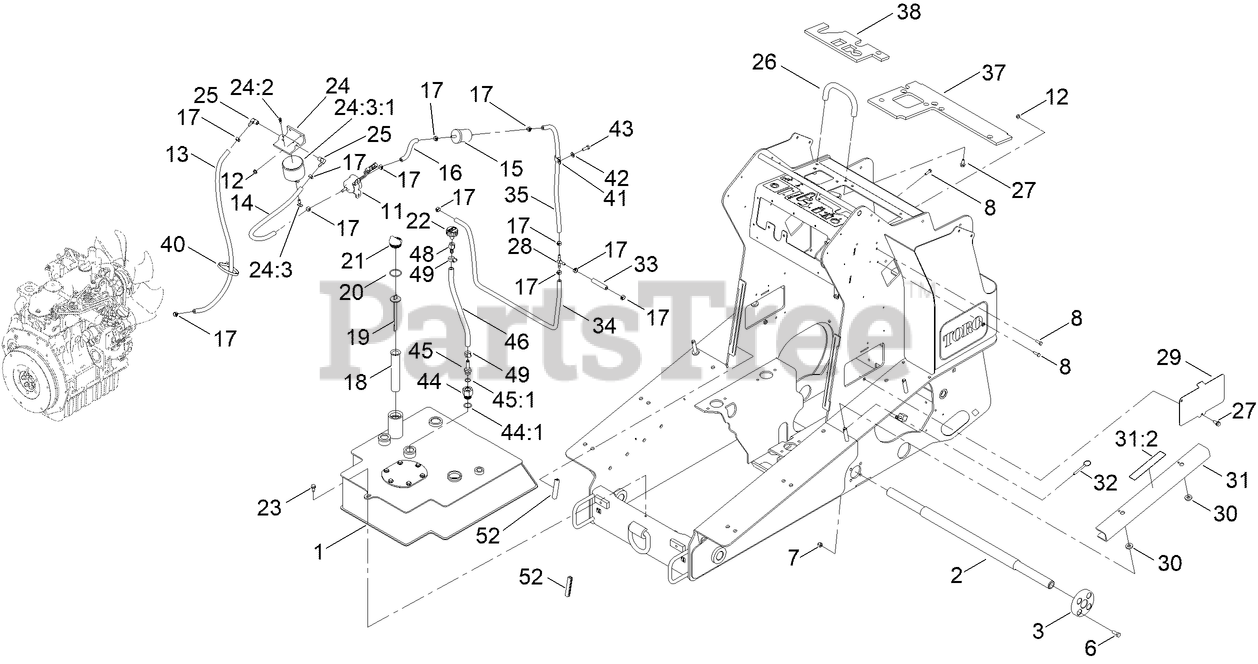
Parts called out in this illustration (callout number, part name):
1	TANK-HYD
2	SHAFT-TRACK
3	HUB-SHAFT
6	SCREW-HH
7	NUT-LOCK, NI
8	SCREW-HH
11	PUMP-FUEL, ELECTRIC
12	NUT-HF
13	HOSE-FUEL
14	HOSE-FUEL
15	FILTER-FUEL
16	HOSE-FUEL
17	CLAMP-HOSE
18	FILTER-SCREEN
19	DIPSTICK
20	O-RING
21	PLUG-PLASTIC
22	BREATHER
23	SCREW-THD ROLL, HWH
24	FILTER HEAD ASM
24:2	VENT-AIR
24:3	ELEMENT-SPIN ON
24:3:1	VALVE-DRAIN
25	FITTING-HYD, 90
26	BAR-REFERENCE
27	SCREW-HHF
28	FITTING-TEE, BARBED
29	PLATE-COVER, ACCESS
30	WASHER-NEOPRENE
31	ARM-LOCKING
31:2	DECAL-DANGER
32	PIN-COTTERLESS
33	HOSE-FUEL
34	HOSE-FUEL
35	HOSE-FUEL
37	FOAM-HEAT SHIELD
38	FOAM-HEAT SHIELD
40	TIE-CABLE
41	CLAMP-R
42	WASHER-FLAT
43	SCREW-HH
44	FITTING-STRAIGHT
44:1	O-RING
45	FITTING-STR
45:1	O-RING
48	FITTING-FEMALE, BARBED
49	CLAMP-HOSE
